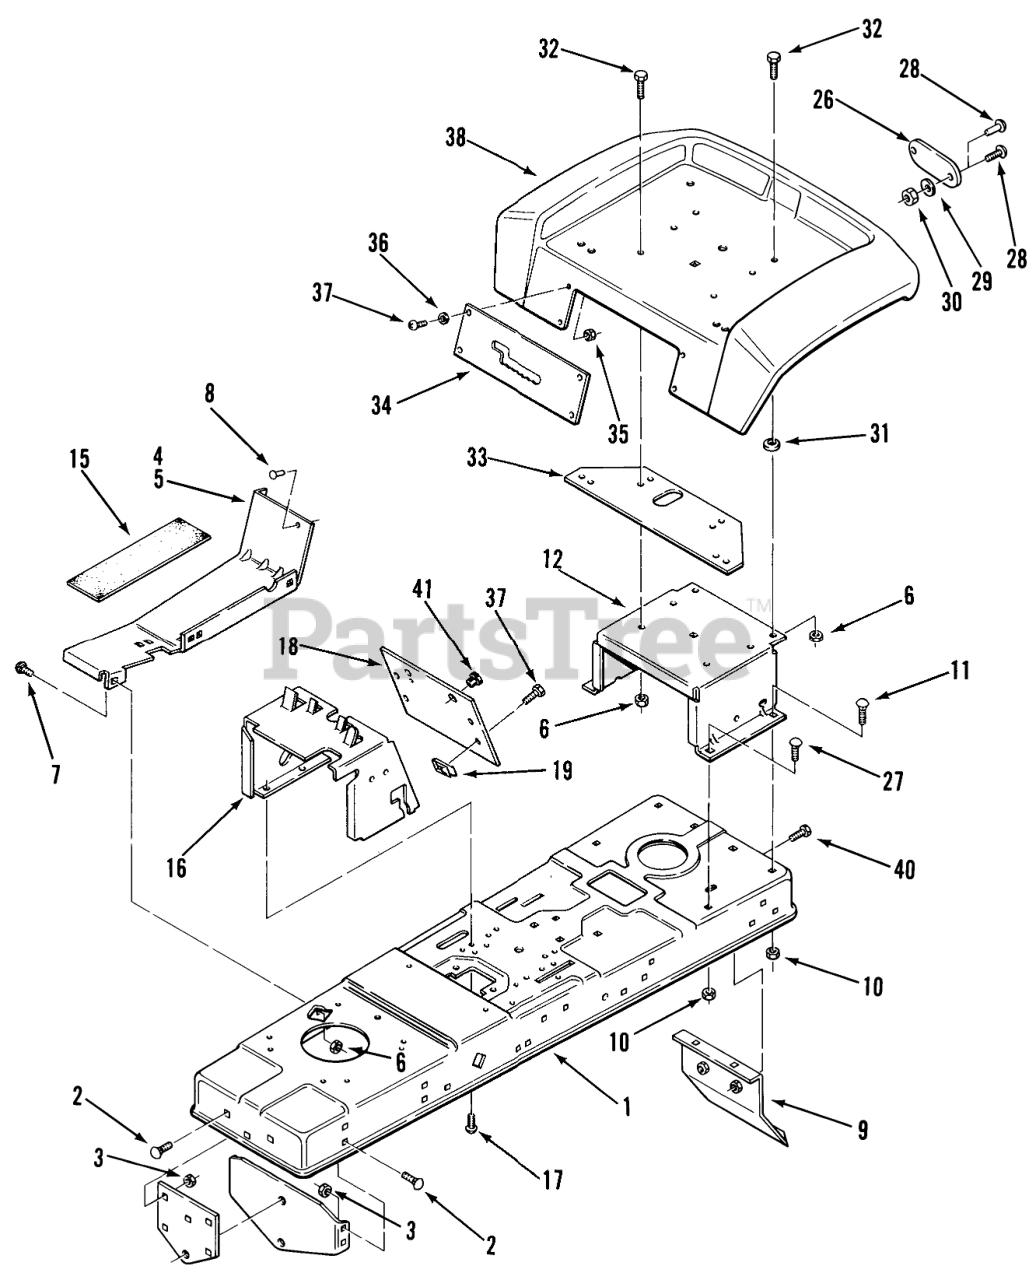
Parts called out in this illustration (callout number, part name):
1	Frame
2	CARRIAGE BOLT -4
3	Nut
4	Footrest RH
5	Footrest LH
6	Nut
7	CARRIAGE BOLT -4
8	BUMPER-RUBBER
9	Hitch Drawbar
10	Nut
11	CARRIAGE BOLT -4
12	SUPPORT-SEAT R
15	PAD-FOOTREST
16	Hoodstand
17	SCREW
18	Hoodstand Plate
26	REFLECTOR-STICK ON
27	Bolt
28	Screw
28	Poprivet
29	Lockwasher
30	Nut
31	WASHER
32	Bolt
32	H H C S
33	PLATE-SEAT R
34	PLATE-SHIFT R
34	Shift Plate
35	Nut
37	Screw
38	Fender
40	Bolt
